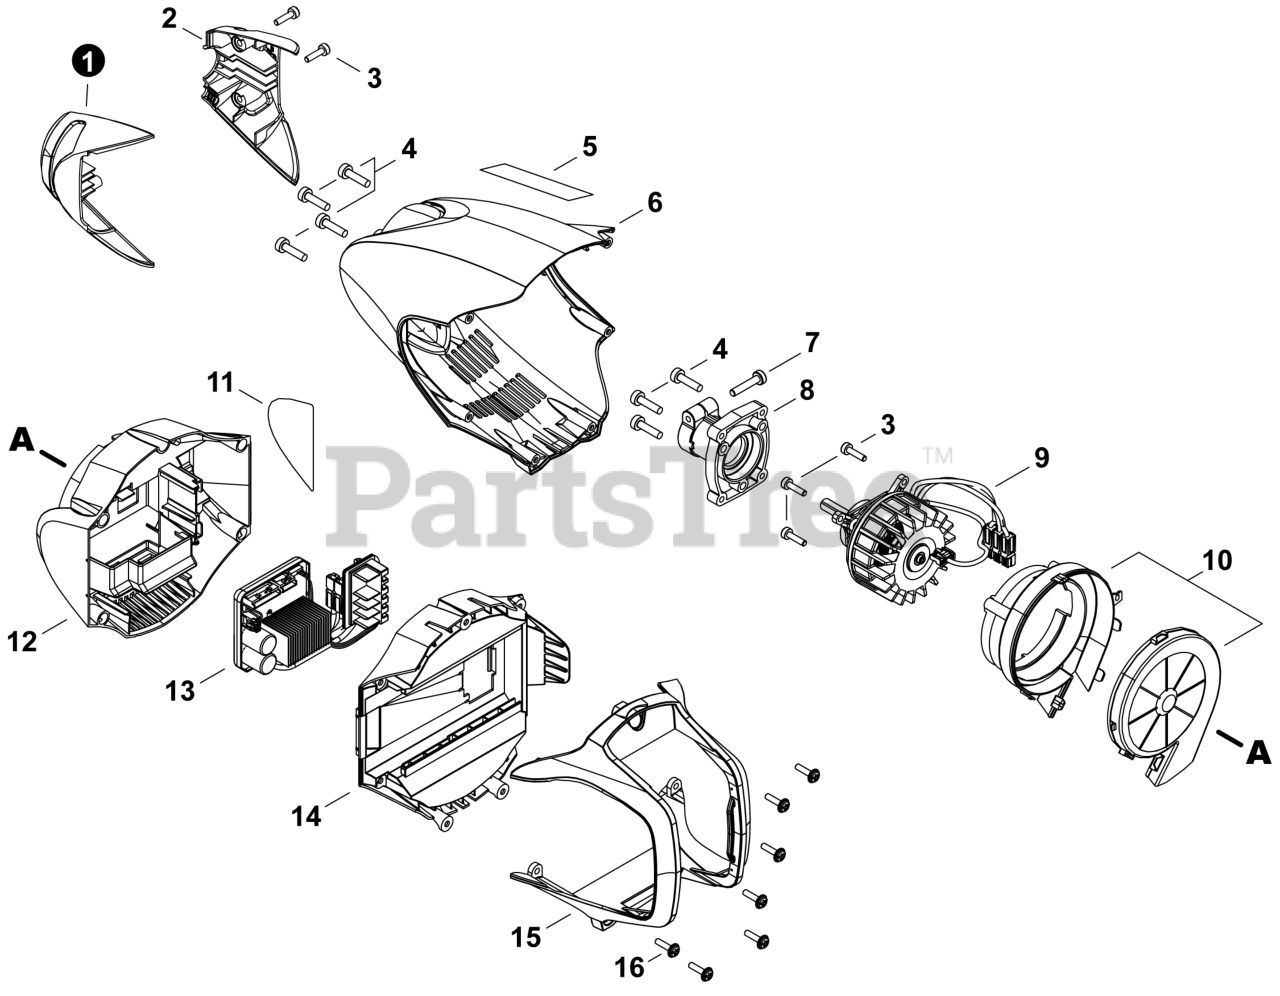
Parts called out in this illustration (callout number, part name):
1	COVER, MOTOR - LEFT
2	COVER, MOTOR - RIGHT
3	BOLT, TORX 4x16
4	BOLT, TORX 5x20
5	LABEL - ECHO
6	COVER, MOTOR
7	BOLT, TORX 5x25
8	HOLDER, MAIN PIPE
9	MOTOR ASSY
10	FAN CASE ASSY
11	LABEL - MODEL DSRM-2600U
12	DUCT, AIR
13	CONTROL BOARD ASSY
14	HOLDER, BATTERY
15	COVER, BATTERY
16	BOLT, TORX 4x16
